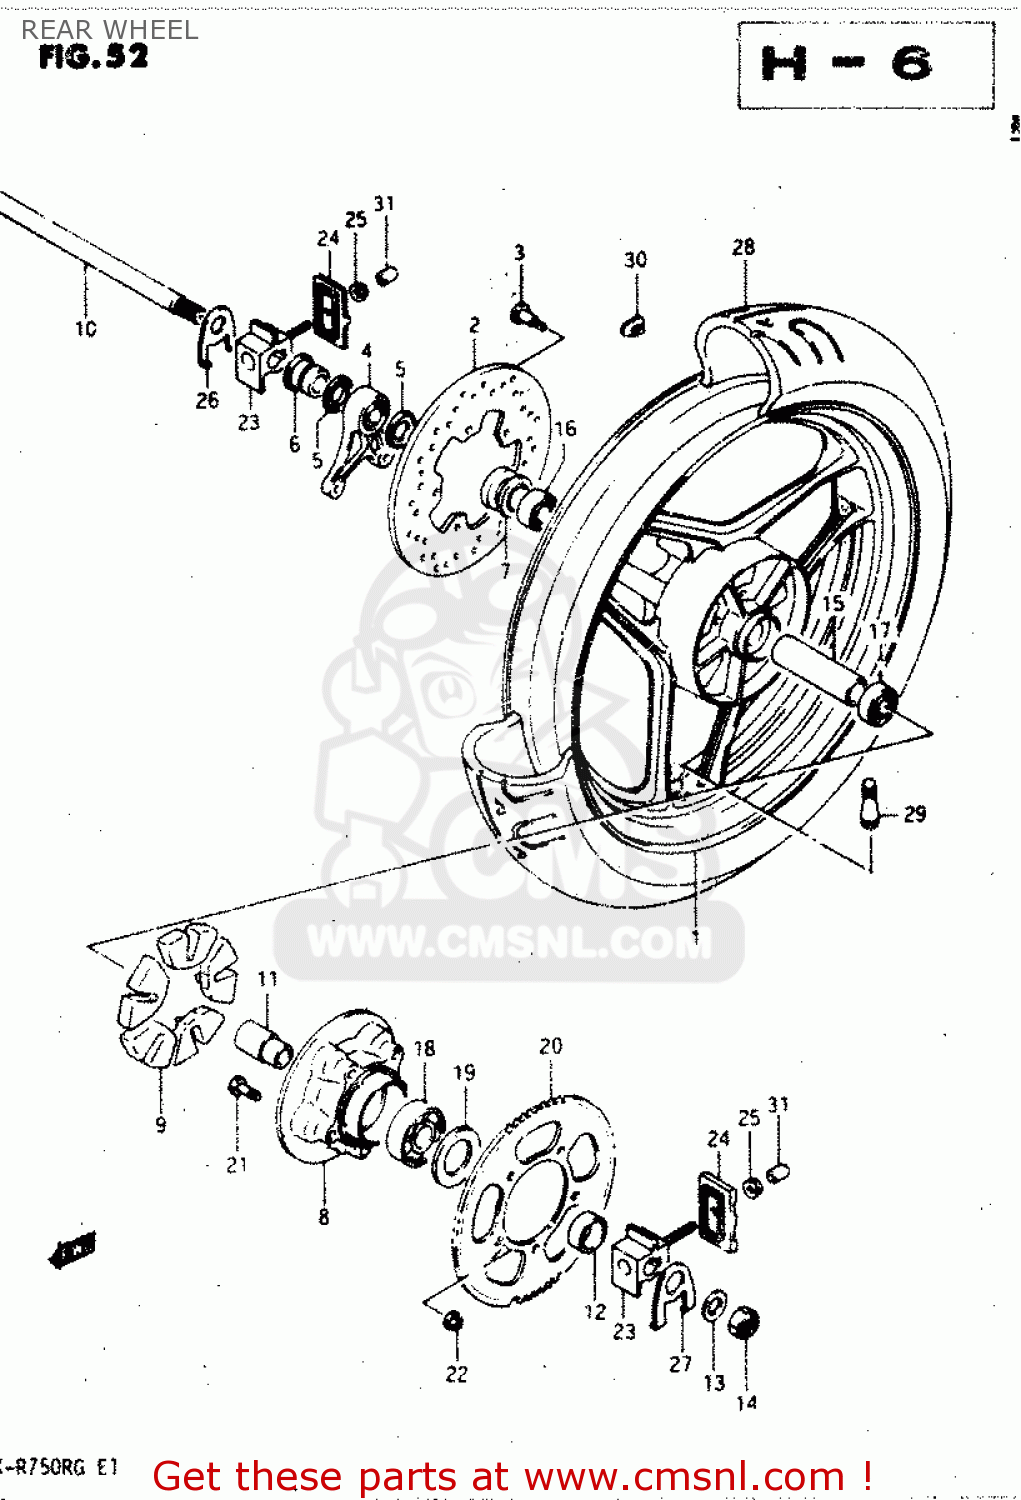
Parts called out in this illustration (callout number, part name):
1	WHEEL,REAR
2	DISC,RR BRAKE
3	BOLT
4	BRACKET,RR CALIPER
5	SEAL,OIL(28X35X5)
6	SPACER,RR CALIPER BRACKET
7	SPACER,RR AXLE,R
8	DRUM,REAR SPROCKET MOUNT
9	ABSORBER,RR HUB SHOCK
10	AXLE,RR
11	RETAINER,RR HUB BEARING
12	SPACER,RR AXLE,L
13	WASHER
14	NUT
15	SPACER,REAR WHEEL HUB
16	BALL BEARING
17	BEARING
18	BEARING
19	SEAL,OIL(35X62X8)
20	SPROCKET,RR(NT:42)
21	BOLT
22	NUT
23	ADJUSTER,CHAIN
24	PLATE,CHAIN ADJUSTER GEAR
25	NUT
26	WASHER,CHAIN ADJUSTER
27	WASHER,CHAIN ADJUSTER
28	TIRE, T/L REAR (140/70V18)
29	VALVE,TIRE
30	BALANCER,WHEEL
31	CAP,CHAIN ADJUSTER
